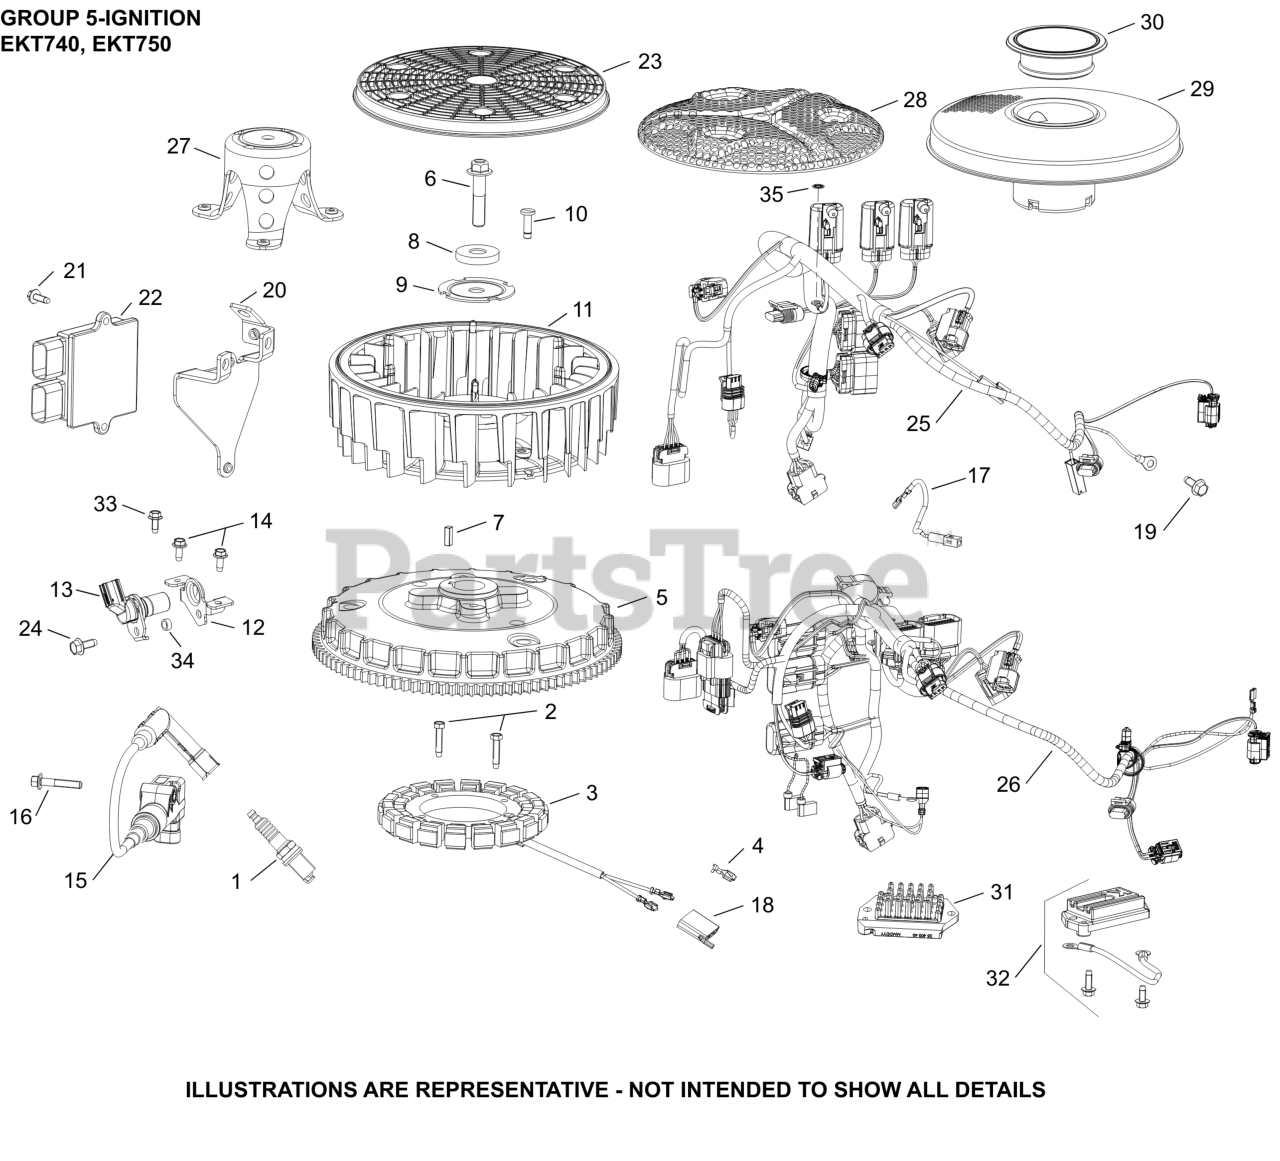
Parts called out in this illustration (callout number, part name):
1	SPARK PLUG, RFI
2	SCREW, THREAD FORMING
3	KIT, 15 / 20 AMP STATOR
5	FLYWHEEL, ASSEMBLY
6	SCREW, HEX FLANGE
7	KEY, SQUARE
8	WASHER, FLAT
9	PLATE, FAN MOUNTING
10	RETAINER, FLYWHEEL FAN
12	BRACKET, SENSOR
13	SENSOR, SPEED
15	COIL, IGNITION - EFI (RFI/EMC)
16	SCREW, HEX FLANGE
17	LEAD, REGULATOR RECTIFIER JUMPER
20	BRACKET, ECU
21	SCREW, THREAD FORMING
22	MODULE, ECU
23	SCREEN, GRASS
24	SCREW, THREAD FORMING
25	HARNESS, WIRING ASSEMBLY (RECOIL)
33	SCREW, THREAD FORMING
35	WASHER, INT TOOTH LOCK #10
